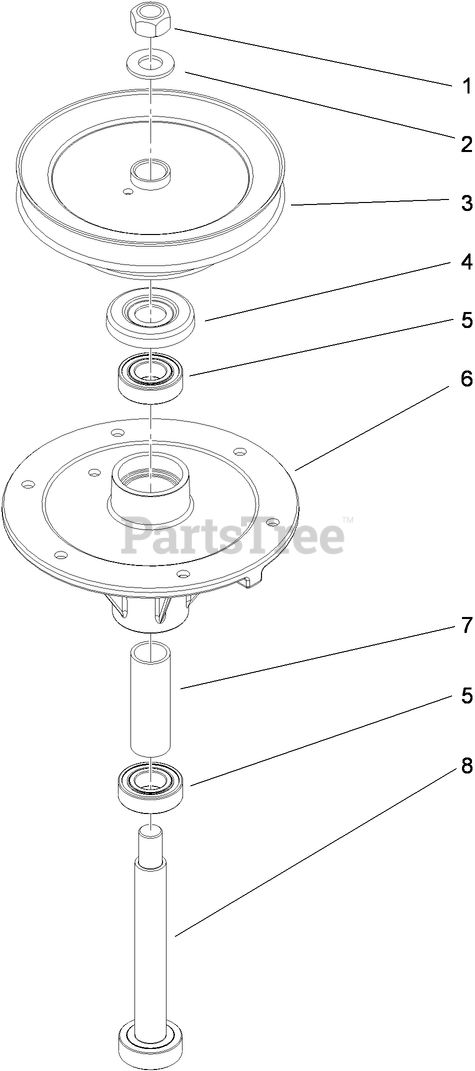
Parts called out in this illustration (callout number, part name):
1	NUT-HEX
2	WASHER
3	PULLEY AND HUB ASM
4	SHIELD-BEARING
5	BEARING-BALL
6	HOUSING-SPINDLE
7	SPACER-BEARING
8	SHAFT-SPINDLE
